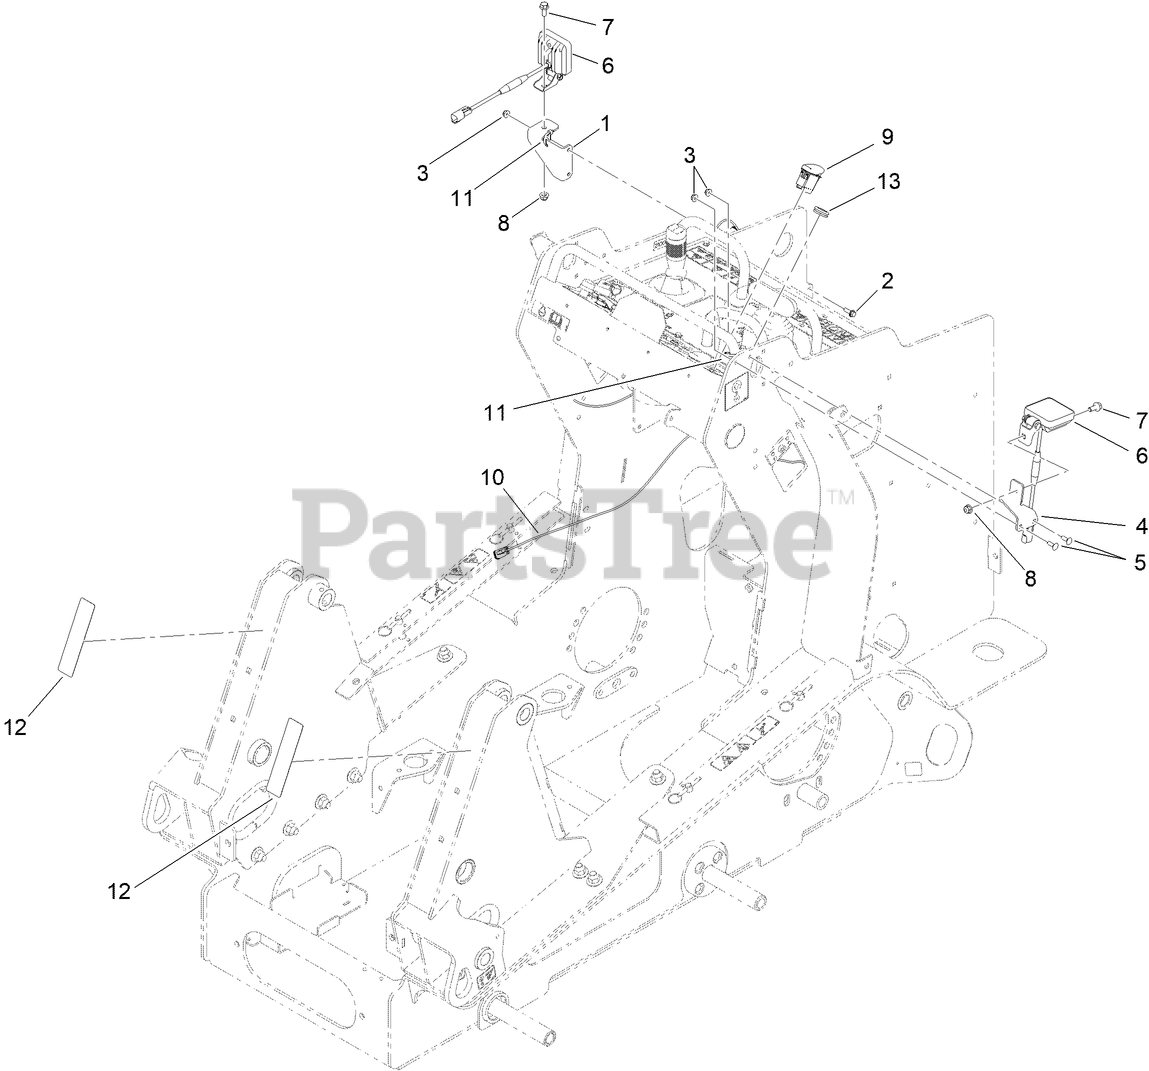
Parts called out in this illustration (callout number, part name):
1	BRACKET-LIGHT
2	SCREW-HHF
3	NUT-HF
4	BRACKET-LIGHT
5	BOLT-CARR
6	LIGHT-WORK, LED
7	SCREW-HHF
8	NUT-HF, NI
9	SWITCH
10	HARNESS-WIRE, WORK LIGHT
11	TIE-CABLE
12	TAPE-REFLECTIVE
13	GROMMET
